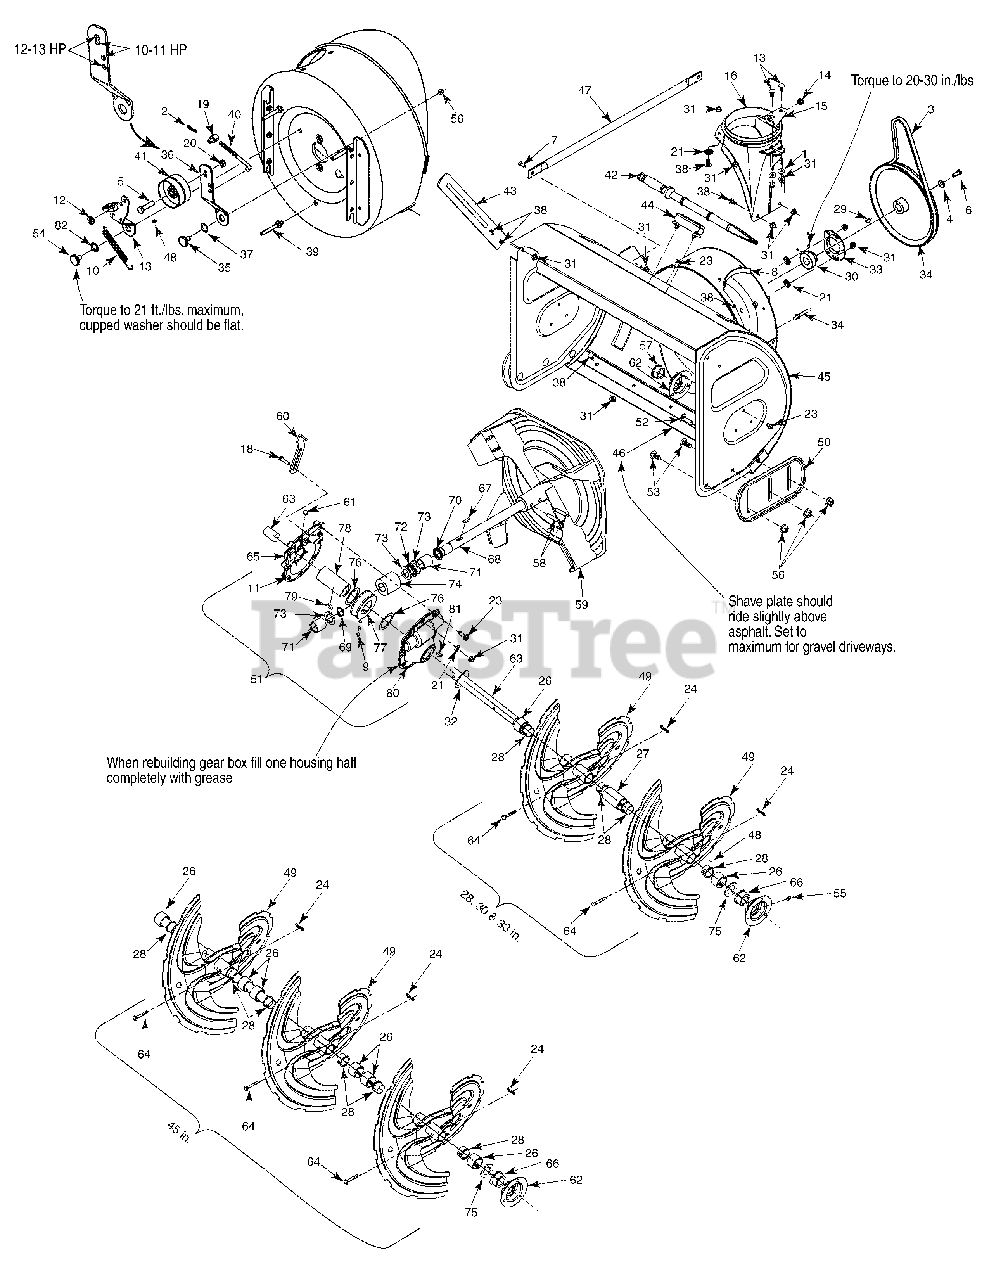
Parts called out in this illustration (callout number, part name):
1	Flat Washer .349 ID x .879 OD x .063
2	Int. Cotter Pin
3	V-Belt 1/2 x 44" Lg.
4	Cupped Washer .345 ID x .88 OD x .06
5	Handle Knob Assembly
6	Hex Screw 5/16-18 x .88
7	Hex Hd Cap Scr. 5/16-18 x .75 Gr. 5
8	Chute Bracket
9	Shell Alvania Grease (3 oz.)
10	Extension Spring .470 Dia. x 4.75
11	Ultra Grey Loctite #5699
12	Flat Washer .344 ID x .75 OD x .120
13	Brake Bracket Ass’y (900 Series)
14	Plastic Bushing .380 ID
15	Chute Brkt.
16	Chute Adapter
17	Cupped Washer .340 ID x .872 OD x .06
18	Hex Screw 5/16-18 x 1.25
19	Adjustment Ferrule
20	Chute Flange Keeper
21	Push-on Nut .25 diam
22	Flange L-Nut 5/16-18 Gr. 5 Nylon
23	Hex TT Screw 3/8-16 x .75
24	Bow Tie Cotter Pin
26	Spacer 1.5 x 1.0 ID x 1.0" Lg.
27	Spacer 1.5 x 1.0 ID x 2.5" Lg.
28	Flange Bushing 1.05 ID x 1.16 OD
29	#9 HI-Pro Key 3/16 x 3/4 Dia HT
30	Self-Aligning Bearing .875 ID
31	Hex Flg. L-Nut 5/16-18 Gr. F Nylon
32	Flat Washer 1.010 x 1.88 x .060
33	Bearing Housing
34	1/2" V-Pulley .875 ID x 10.12 OD
35	Shoulder Scr .625 Dia x .170
36	Auger Idler Bracket
37	Wave Washer .625 ID x .885 OD x .015
38	Carriage Bolt 5/16-18 x .75
39	Screw 5/16-18 x .43
40	Auger Idler Rod
41	Flat Idler Pulley
42	Cleanout Tool
44	Cleanout Tool Mount
51	Worm Gear Box Ass’y
51	Worm Gear Box Ass’y (w/grease fitting)
52	Carriage Bolt 3/8-16 x 1.00 Gr. 5
53	Carriage Bolt 3/8-16 x .75" Lg.
54	Shoulder Scr .625 Dia x .170
55	Grease Fitting (optional)
56	Hex Flange L-Nut 3/8-16 Gr. F Nylon
57	Flange bearing w/flats
58	Spring Spirol Pin Heavy - 5/16 dia x 1.7
60	Gear Housing Support Bracket
61	Barbed Plug
62	Bearing Housing
63	Spiral Axle 28 inches
64	Shear Pin 5/16-18 x 1.75
65	Gear Housing Half - RH
66	Flange Bearing
67	#9 HI-Pro Key 3/16 x 3/4 Dia HT
68	Auger Drive Shaft
69	Snap Ring for .875 dia. shaft
70	Oil seal for .875 ID Garlock (76 x 6133)
71	Sleeve Bearing .875 ID
72	Thrust Bearing .88 ID x 1.44 OD x .078
73	Flat Washer .88 ID x 1.4 OD x .125
74	Worm Gear LH Double Thread
75	Spacer
76	Flat Washer 1.5 ID x 2.0 OD x .03
77	Worm Gear LH Double Thread (Bronze)
78	Worm Gear Shaft
79	#91 Woodruff Key 1/4 x 3/4 Dia.
80	Gear Housing Half LH
81	#91 Woodruff Key 1/4 x 3/4 Dia.
